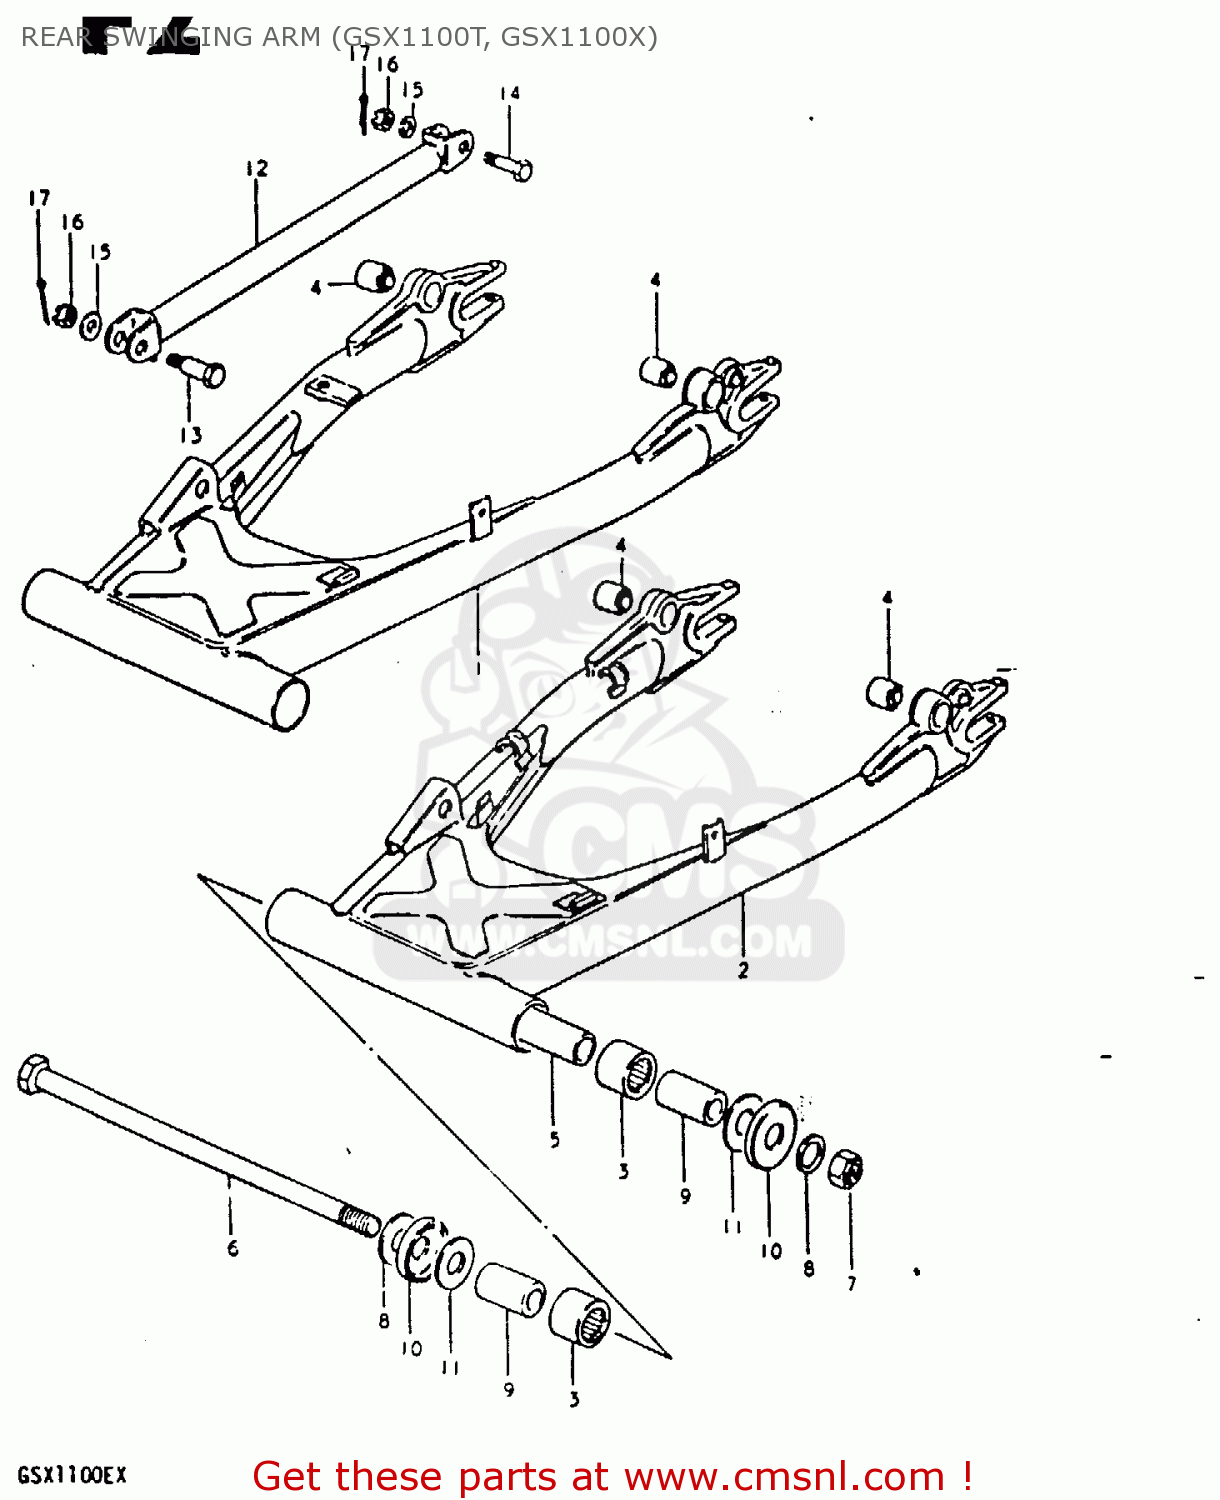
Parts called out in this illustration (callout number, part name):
1	SWING ARM ASSEMBLY,REAR
2	SWING ARM ASSEMBLY,REAR
3	BEARING(25X33X30)
4	BUSH
5	SPACER,RR SWGARM PIVOT CTR
6	SHAFT,REAR SWING ARM
7	NUT 16MM
8	WASHER
9	SPACER,RR SWGARM PIVOT
10	COVER,REAR SWING ARM DUST
11	WASHER
12	TORQUE LINK, REAR
13	BOLT
14	BOLT(10X39)
15	WASHER
16	NUT
17	PIN 20X20
